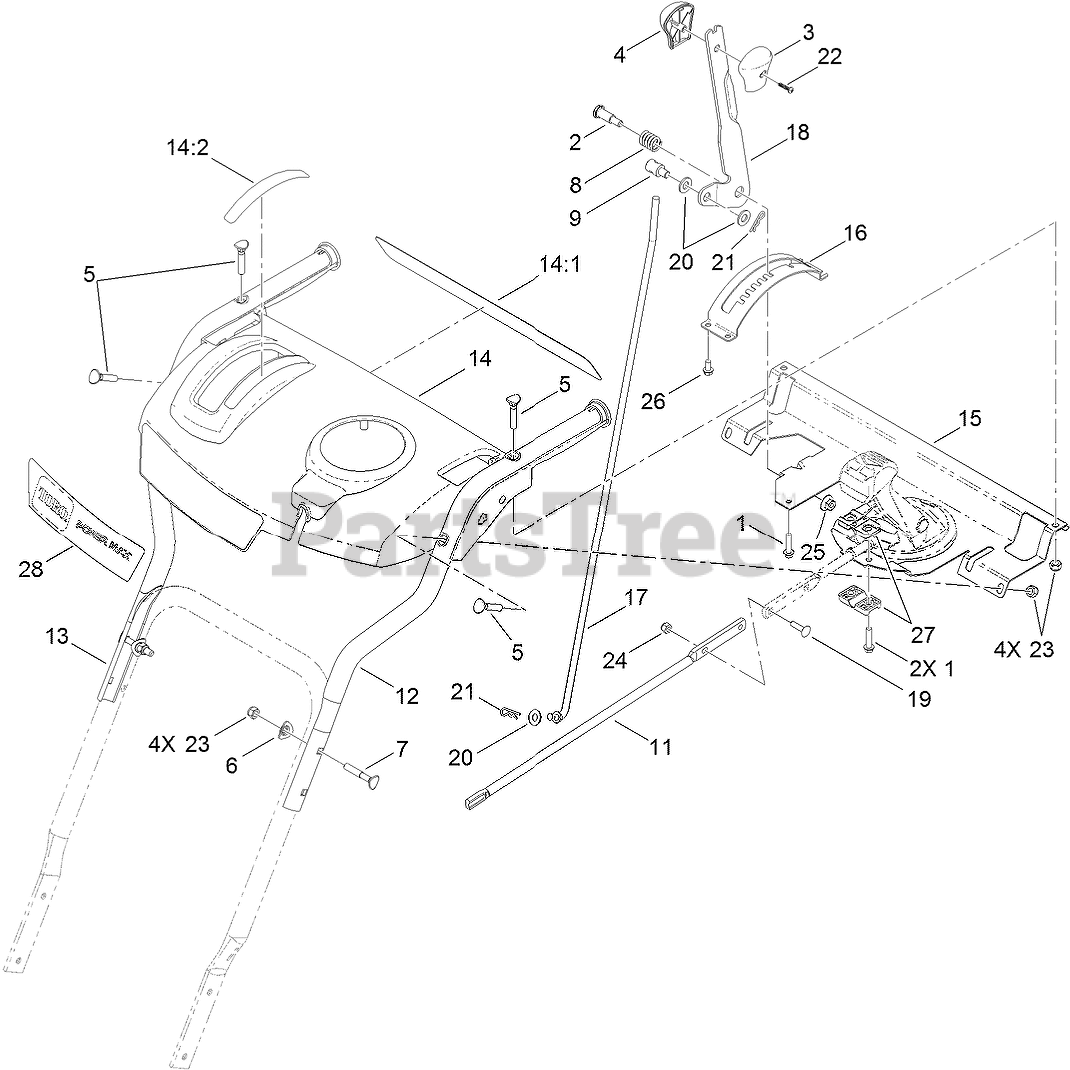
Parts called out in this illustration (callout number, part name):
1	SCREW-PLASTITE
2	SCREW-SHOULDER
3	KNOB-SHIFT, LH
4	KNOB-SHIFT, RH
5	SCREW-HANDLE
6	WASHER
7	SCREW-HANDLE
8	SPRING-COMPRESSION
9	TRUNNION-ROD
11	ROD-CHUTE, FRONT
12	HANDLE-UPPER, LH
13	HANDLE-UPPER, RH
14	PANEL-CONTROL, MASTER
14:1	DECAL-SAFETY
14:2	DECAL-CONTROL, SPEED
15	SUPPORT-PANEL, CONTROL
16	MOUNT-SELECTOR, SPEED
17	ROD-SELECTOR, GEAR
18	SELECTOR-SPEED
19	SCREW-CARR
20	WASHER-FLAT
21	PIN-COTTER
22	SCREW-PPH
23	NUT-LOCK, NI
24	NUT-LOCK, NI
25	NUT-HF
26	SCREW-PLASTITE
27	SUPPORT-ROD
28	DECAL-MODEL
